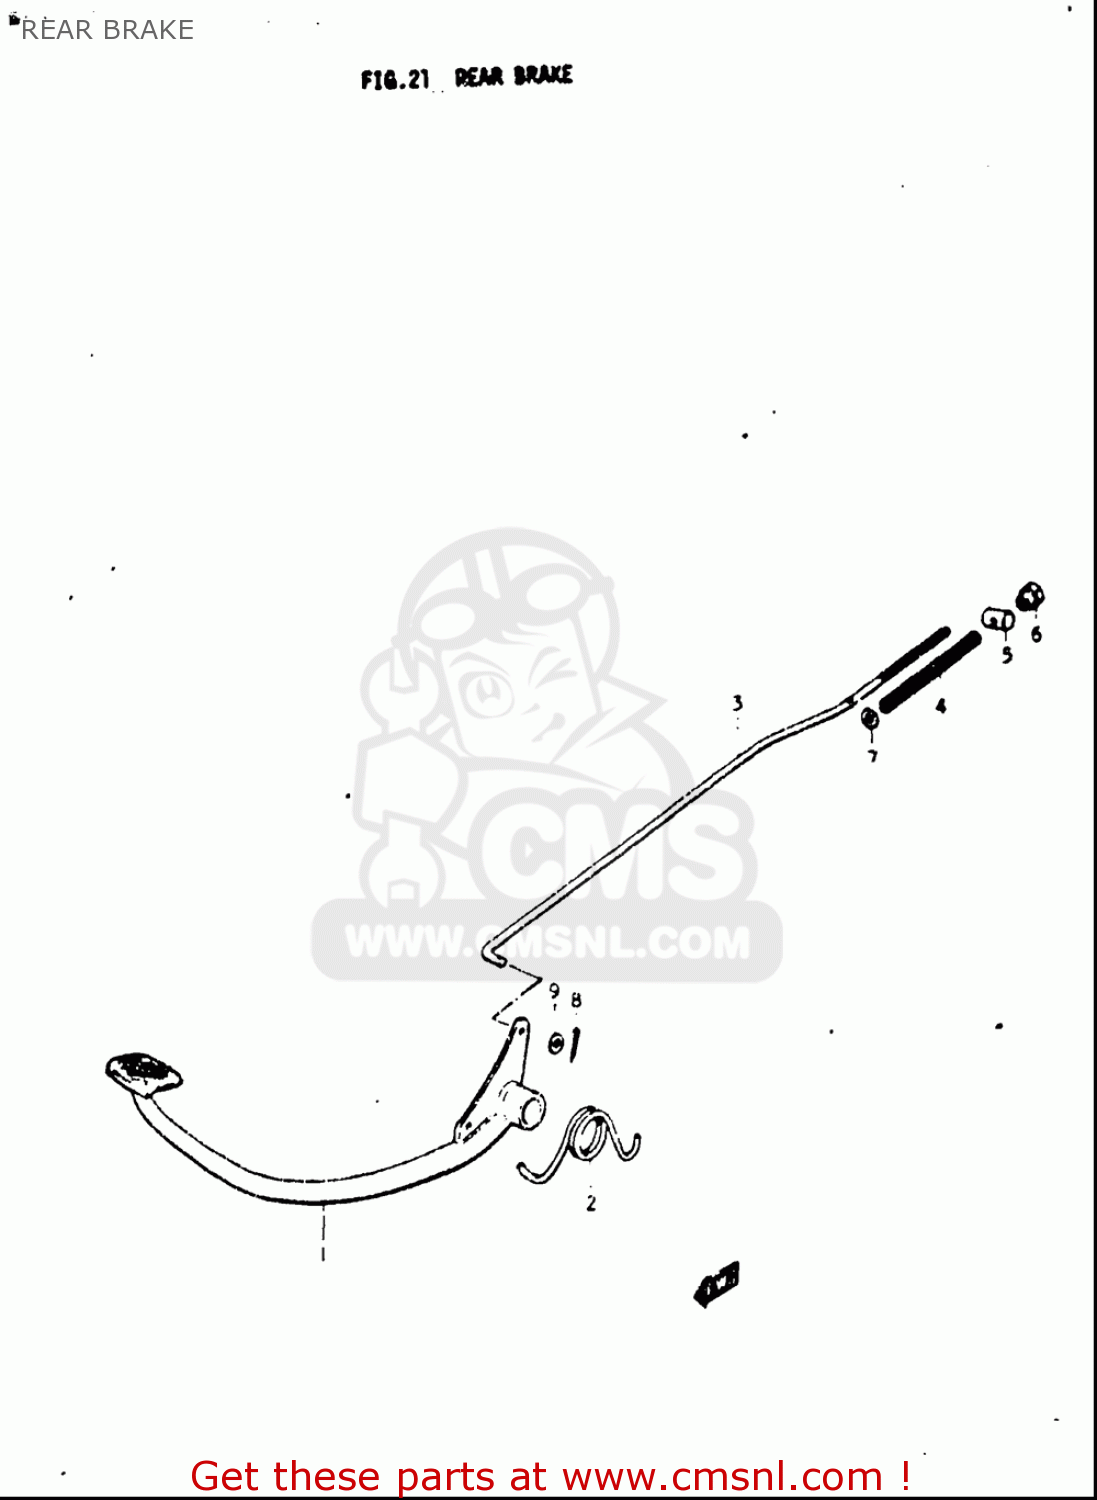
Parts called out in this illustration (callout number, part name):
3	ROD ASSY,RR BRAKE
4	SPRING
5	PIN(11X18)
6	NUT
7	WASHER
8	PIN
9	WASHER
